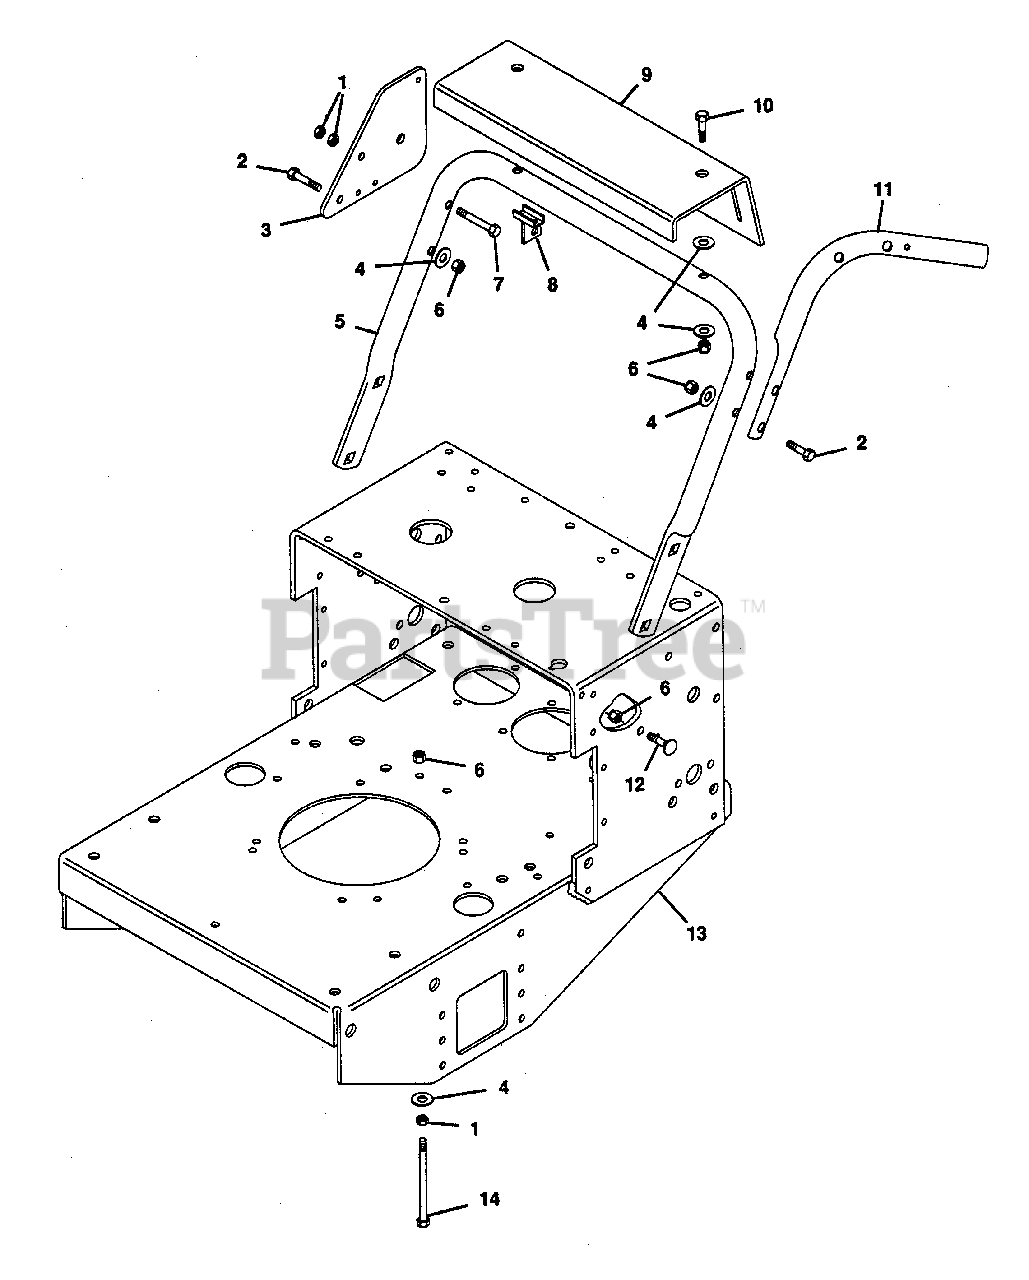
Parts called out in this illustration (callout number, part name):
1	Nut, Hex 3/8-16
2	Bolt, Hex 3/8-16x2.25
3	Plate, Speed Control Lever
4	Washer, Flat .406x.812x.065
5	Tube, Handlebar Mounting
6	Nut, Lock 3/8-16
7	Bolt, Hex 3/8-16x2.50
8	Weldment, PTO Lever Mounting
9	Panel, Silk Screen
10	Bolt, Hex 3/8-16x2.00
11	Handlebar, L.H.
11	Handlebar, R.H.
12	Bolt, 3/8-16x1.00 Rd Hd Sq Nk
13	Weldment, Frame
14	Bolt, Hex 3/8-16x4.00
